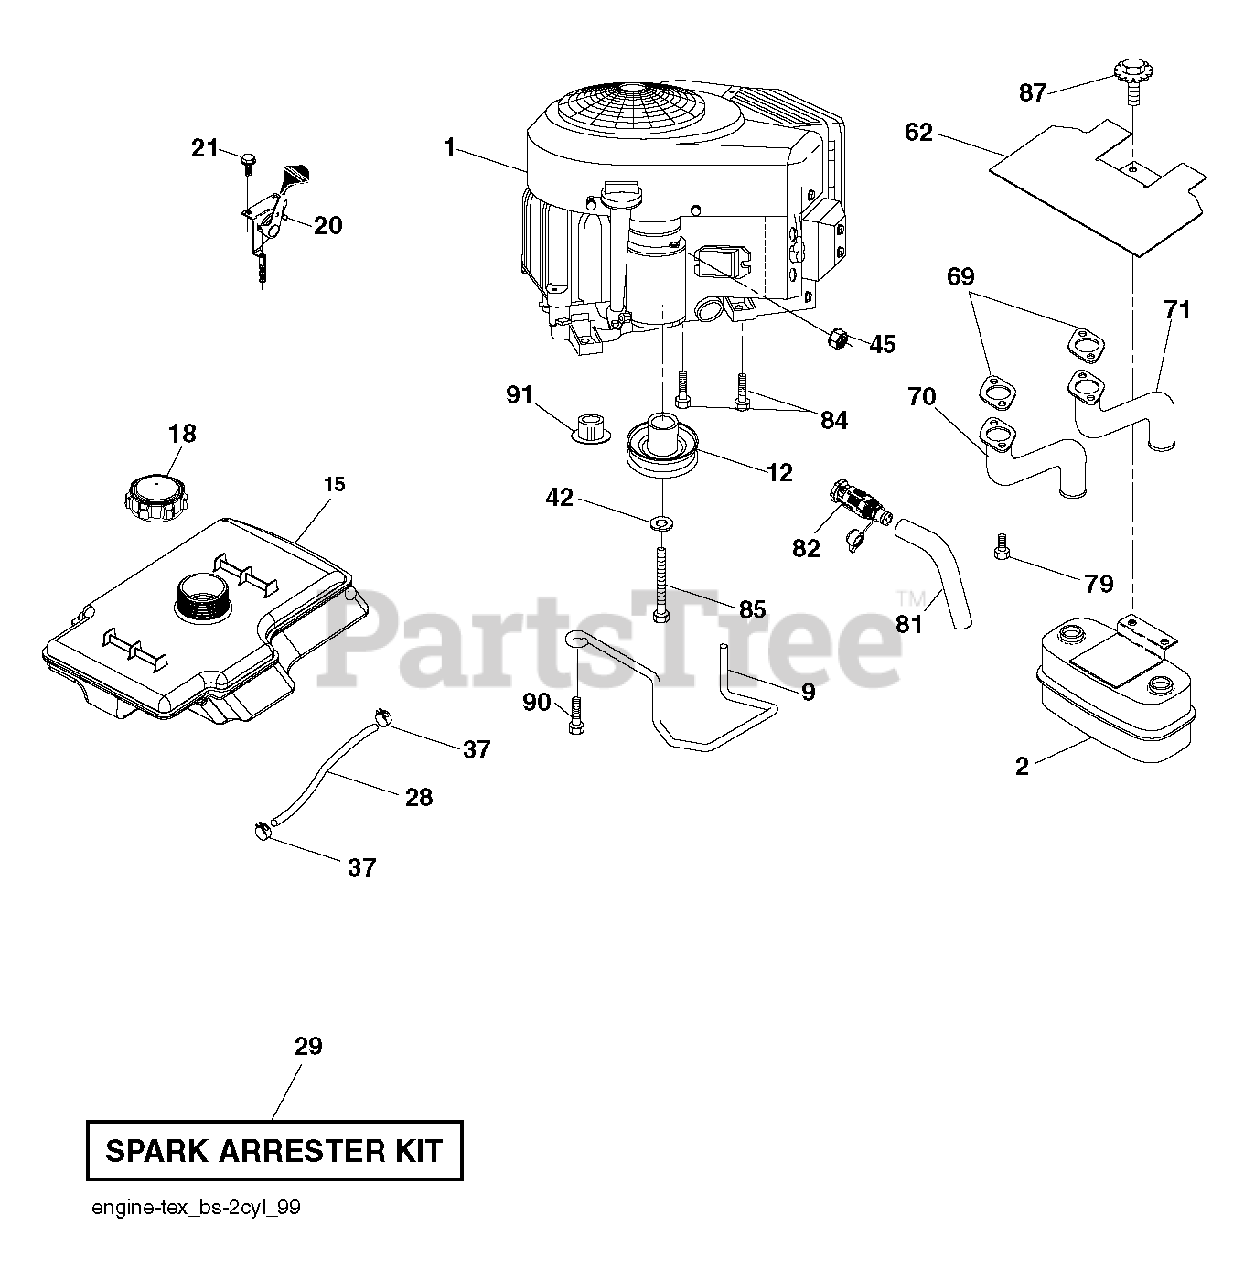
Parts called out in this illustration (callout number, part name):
2	MUFFLER.TWIN.CYL.LOW.TONE
9	KEEPER.BELT.ENGINE.3.25
12	PULLEY.ENGINE.5.0.PD
18	CAP.ASM.FUEL.TANK.3"BLACK
20	CONTROL.TH/CK.COBRA.B&S.TWN.
21	SCREW.#10 X 0.750.BOS (2 2)
28	Fuel Line
29	KIT.SPARK ARRESTOR(392390 B&S)
37	HOSE CLAMP
42	LOCKWASHER
45	NUT
62	SHIELD.HEAT.MUFFLER
69	GASKET.MUFFLER
70	EXHAUST.TUBE.LH.BS/TWIN
71	EXHAUST.TUBE.RH.B&S.TWIN.INTEK
79	SCREW.SOCKET.HEAD.5/16-18
81	TUBE, DRAIN OIL ASM.
82	VALUE.OIL.DRAIN
84	SCREW.3/8-16
85	BOLT HEX 7/16-20X4-1/4"
87	BOLT, 5/16-18 X 1 3/4
90	SCREW 3/8-16X1
91	BUSHING.1.375OD
